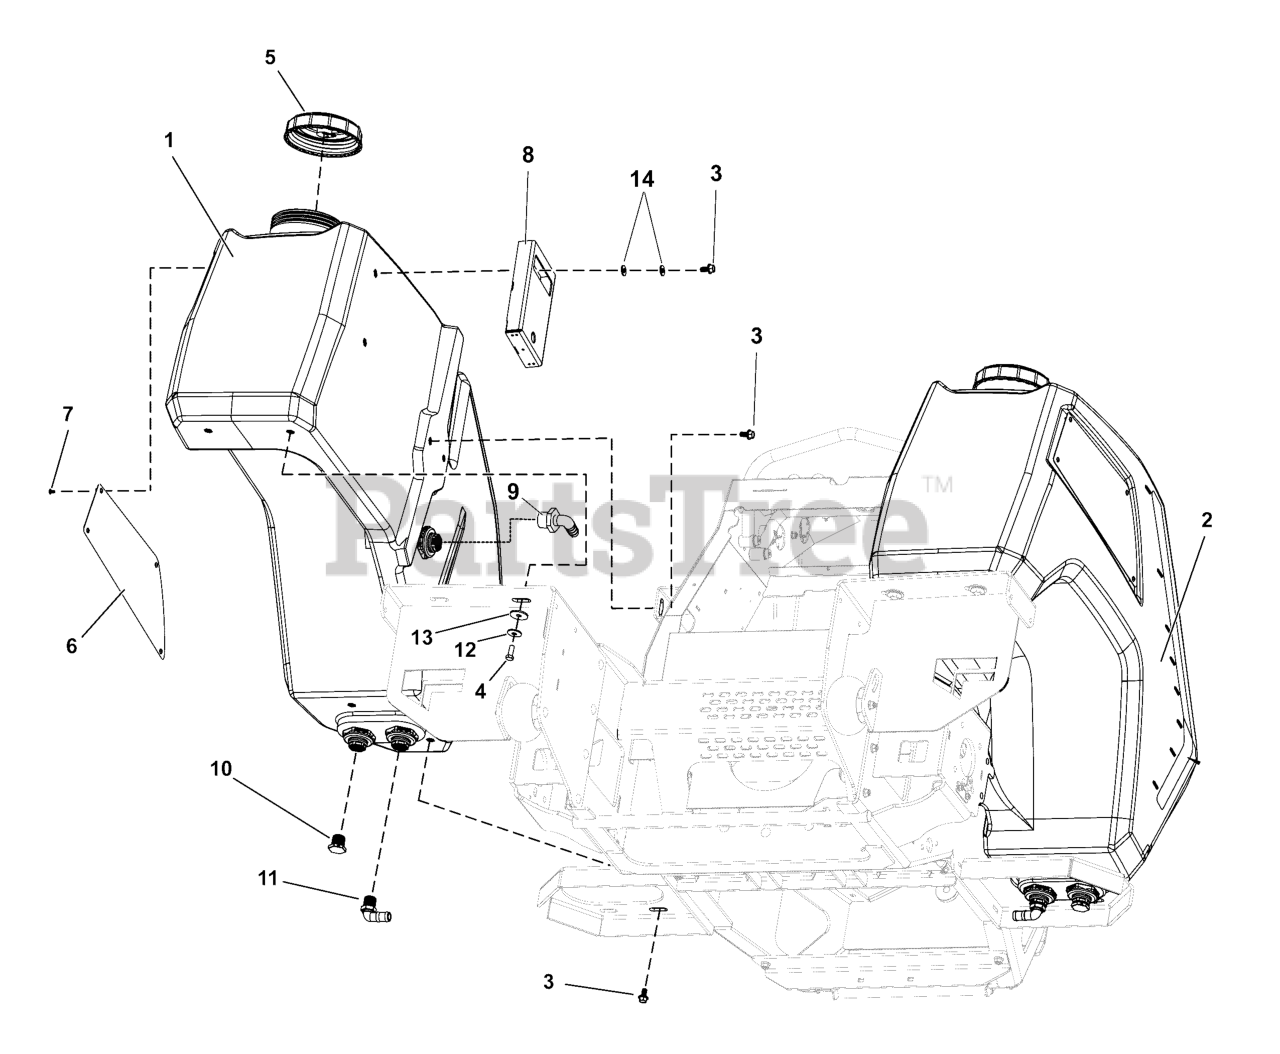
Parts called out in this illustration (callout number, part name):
1	TANK, LIQUID STYLED 40 GAL LH
2	TANK, LIQUID STYLED 40 GAL RH
3	SCR-CAP, HSWH .375"-16 X .750" SS188
4	SCR-CAP, HEX .375"-16 X 1.000" SS188
5	LID, TANK, SPRAY (G0134)
6	PLATE, TANK BRANDING
7	SCR-CAP, SBWH #10-24 X .375" SS188
8	WELD, FLAG HOLDER
9	FITTING, 3/4 MPT - 1/2 BARB, 90 ELBOW
10	FTG, CAP 3/4" MNPT PP
11	FTG, ELBW 90° 3/4" MNPT - 3/4" HB BPP
12	WSHR-SS, BLV .386"X1.063"X.083" 17-7PH
13	WSHR-SS, FLT .405"X1.500"X.120" SS188
14	WSHR-SS, FLT .375"X.875"X.083" USS
